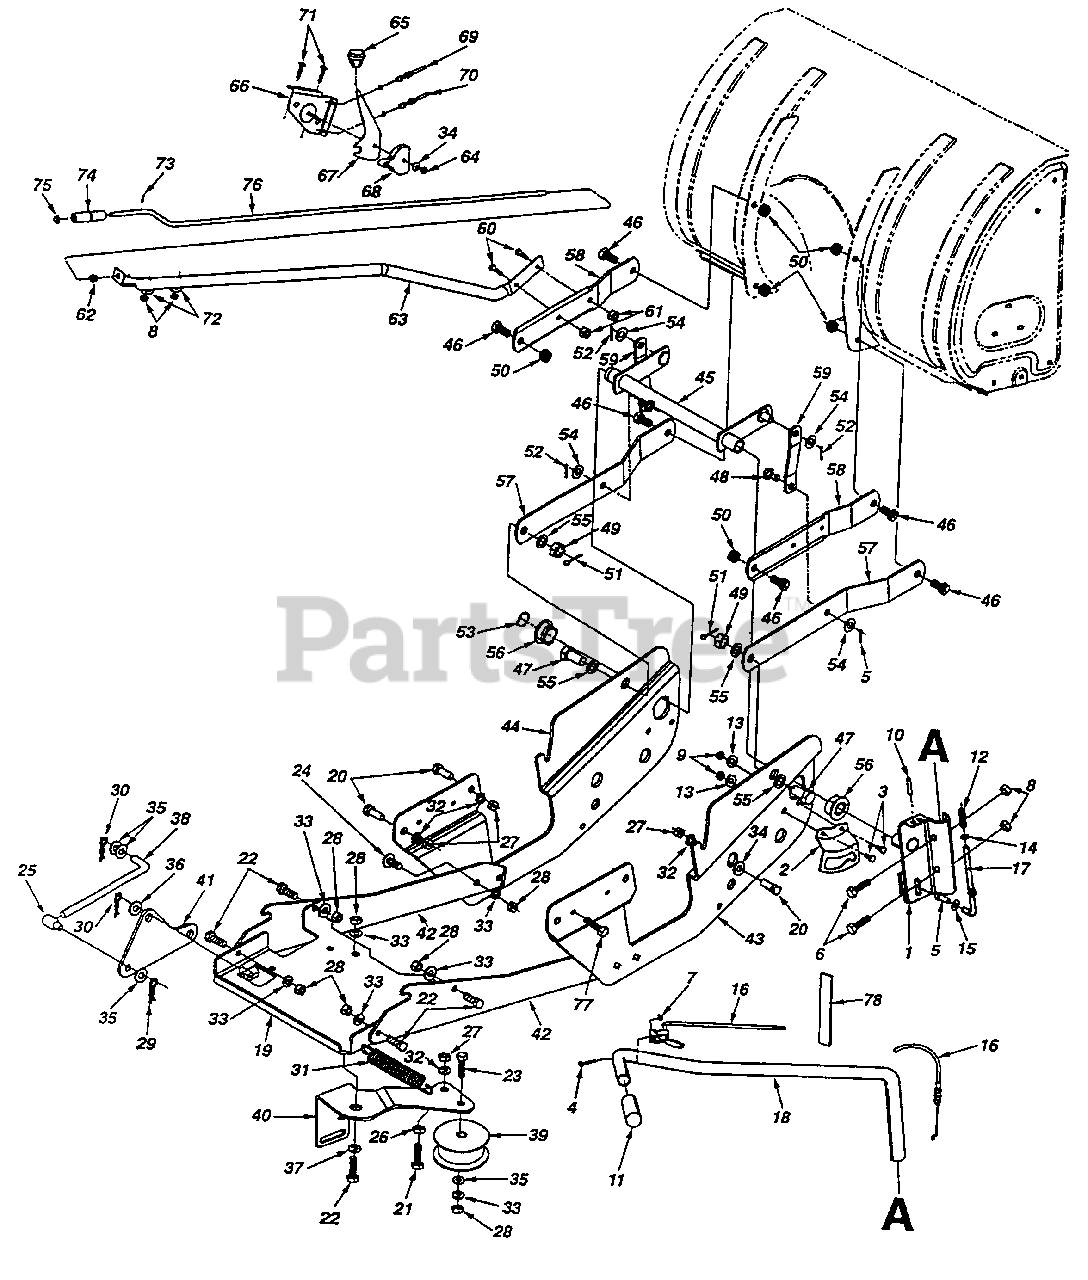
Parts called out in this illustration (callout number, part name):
4	Oval C-Sunk Scr. #10-24 x 1.36" Lg.
5	Hex Wash. Hd. Scr. 5/16-18 x .87" Lg.
6	Hex Bolt 5/16-18 x 1.75" Lg.
7	Flat Weld Nut #10-24 Thd.
8	Hex Flange L-Nut 5/16-18 Thd.
9	Hex Nut 5/16-18 Thd. (Gr. 5)
10	Spring Pin 1.5" Lg.
12	Ext. Spring 1.75" Lg.
13	L-Wash. 5/16 I.D.
14	Fl-Wash .385" I.D. x .62" O.D.
15	Fl-Wash .194" I.D. x.62" O.D.
16	Lift Cable
17	Lift Index Rod
18	Lift Handle Tube
21	Hex Bolt 5/16-18 x 2.25" Lg.
22	Hex Bolt 3/8-16 x 1" Lg.
23	Hex Bolt 3/8-16 x 2" Lg. (Gr. 5)
24	Carriage Bolt 3/8-16 x 1" Lg. (Gr. 5)
25	Ferrule 3/8-24 Thd,
26	Hex Jam Nut 5/16-18 Thd.
27	Hex Nut 5/16-18 Thd. (Gr. 5)
28	Hex Nut 3/8-16 Thd. (Gr. 5)
29	Hairpin Clip 1.42" Lg.
30	Hairpin Clip 1.62" Lg.
31	Ext. Spring 5.5" Lg.
32	L-Wash. 5/16" I.D.
33	L-Wash. 3/8" I.D.
34	Bell-Wash .345" I.D. x.88" O.D.
35	Fl-Wash .406" I.D. x .875" O.D.
36	Fl-Wash .531" I.D. x 1" O.D.
37	Shoulder Spacer
38	Adj. Clutch Control Rod
39	Idler Pulley
47	Hex Bolt 5/8-18 x 1.25" Lg. (Gr. 5)
48	Lift Bracket Pin
49	Hex Slotted Nut 5/8-18 Thd.
50	Hex Cent. L-Nut 1/2-13 Thd. (Gr. 5)
51	Cotter Pin 1.25" Lg.
52	Cotter Pin,75" Lg.
53	Snap Ring
54	Fl-Wash .51" I.D. x 1" O.D.
55	Fl-Wash. 5/8" I.D. x 1" O.D.
56	Flange Bearing w/Flats
61	Hex Flange L-Nut 5/16-18 Thd.
62	Plastic Bushing
65	Knob
68	Cable Guide
69	Chute Control Cable w/Clip
70	Chute Control Cable
71	Carriage Bolt 5/16-18 x l.5" Lg.
72	Saddle Wash .32" I.D.
73	Roll Pin .63" Lg.
74	Chute Crank Knob
75	Push Cap 3/8" Rod
76	Chute Crank Rod
77	Hex Wash. Hd. Tap Scr. 1/4-20 x.75" Lg.
78	Cable Tie
